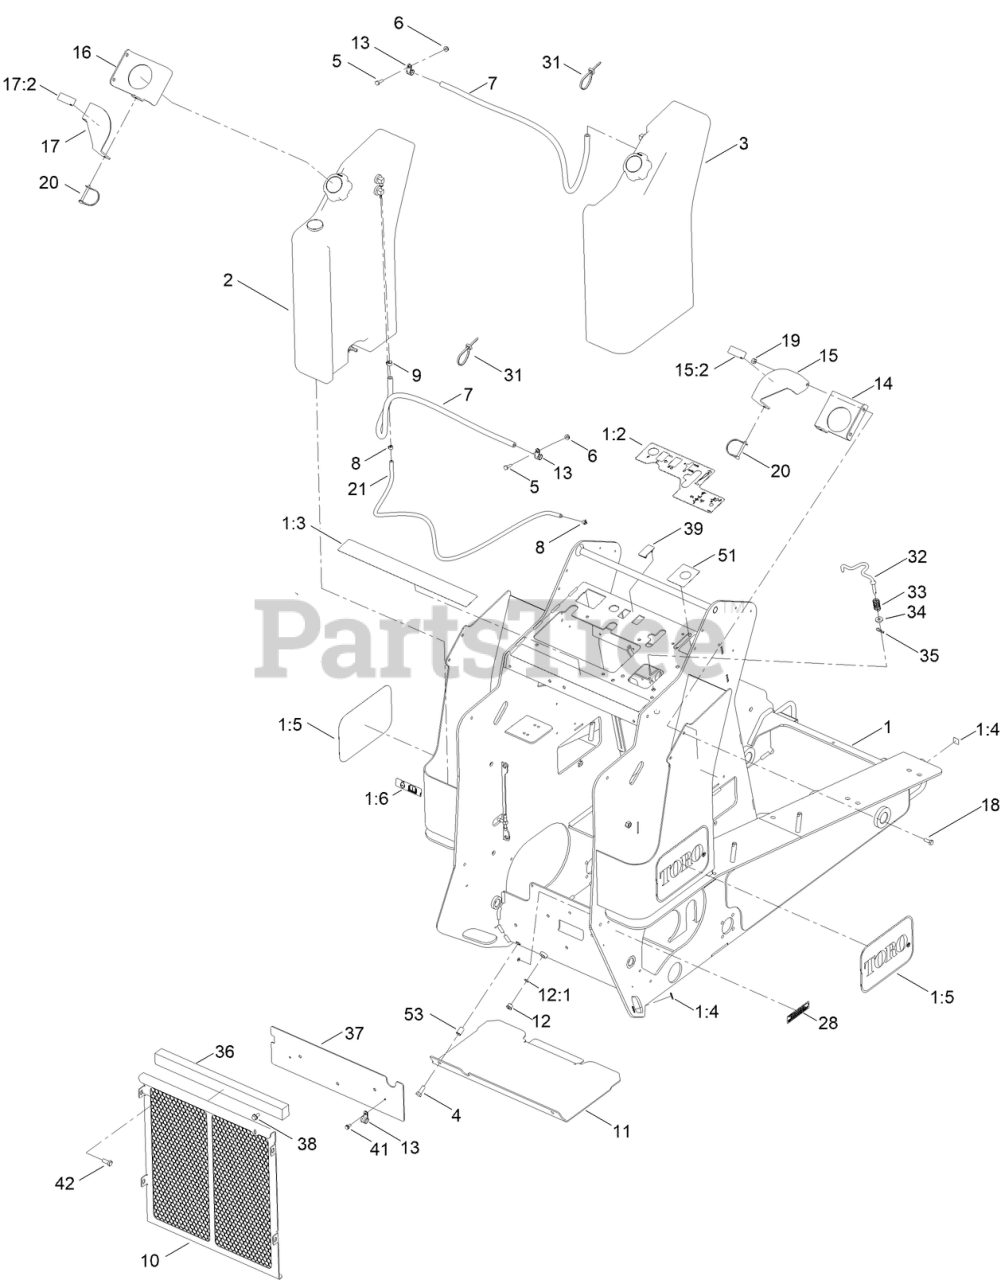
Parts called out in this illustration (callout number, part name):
1	TX1000 FRAME ASM (SERVICE)
1:2	DECAL-CONTROL PANEL
1:3	DECAL-SAFETY
1:4	DECAL-POINT, LIFT
1:5	DECAL
1:6	DECAL-RADIATOR FILL
2	LH FUEL TANK ASM
3	RH FUEL TANK ASM
4	SCREW-HH
5	SCREW-HH
6	NUT-HF
7	HOSE-FUEL
8	CLAMP-HOSE
9	CLAMP-HOSE
10	RADIATOR COVER ASM
11	COVER-BOTTOM
12	PLUG-HEX, HOLLOW
12:1	O-RING
13	CLAMP-R
14	PLATE-HOLD DOWN, RH
15	PLATE-LOCK, FUEL CAP, RH
15:2	DECAL-DIESEL
16	PLATE-HOLD DOWN, LH
17	PLATE-LOCK, FUEL CAP, LH
17:2	DECAL-DIESEL
18	SCREW-HH
19	NUT-LOCK, NI
20	PIN-HITCH
21	HOSE-FUEL
28	DECAL-ARRESTOR, SPARK
31	TIE-CABLE
32	ROD-INTERLOCK
33	SPRING-CONTROL
34	WASHER-FLAT
36	SEAL-FOAM
37	PLATE-COVER
38	SCREW-HWHTF
39	PLUG-HOLE
41	SCREW-HWH
42	SCREW-HH
51	DECAL-IGNITION SWITCH
53	NUT-CLINCH
